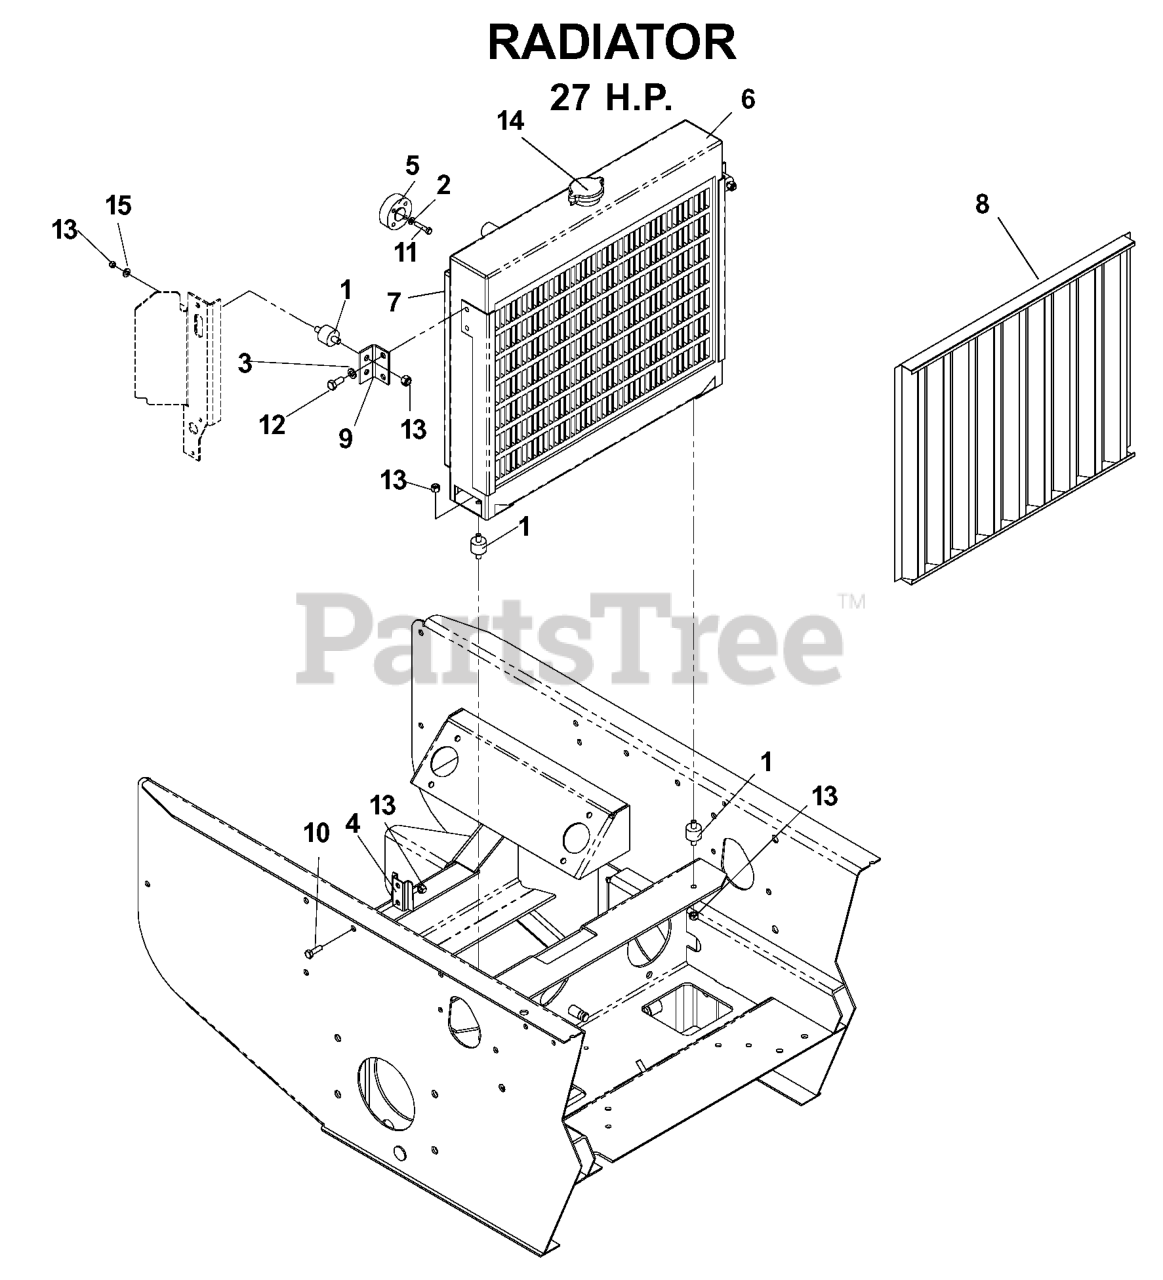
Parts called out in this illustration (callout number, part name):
2	LOCKWASHER 1/4"
3	WASHER.LOCK.HVY.HLCL.SPR.5/16
4	MOUNTING BRACKET
5	FAN SPACER
8	DEBRIS GUARD
9	BRACKET ISO
10	HCS 5/16C X 1
11	BOLT - M6-1.0 X 30MM GR 8
12	HCS 5/16C X 3/4
13	NUT 5/16 NYLOC
14	RADIATOR CAP
15	FLAT WASHER 5/16 SAE
